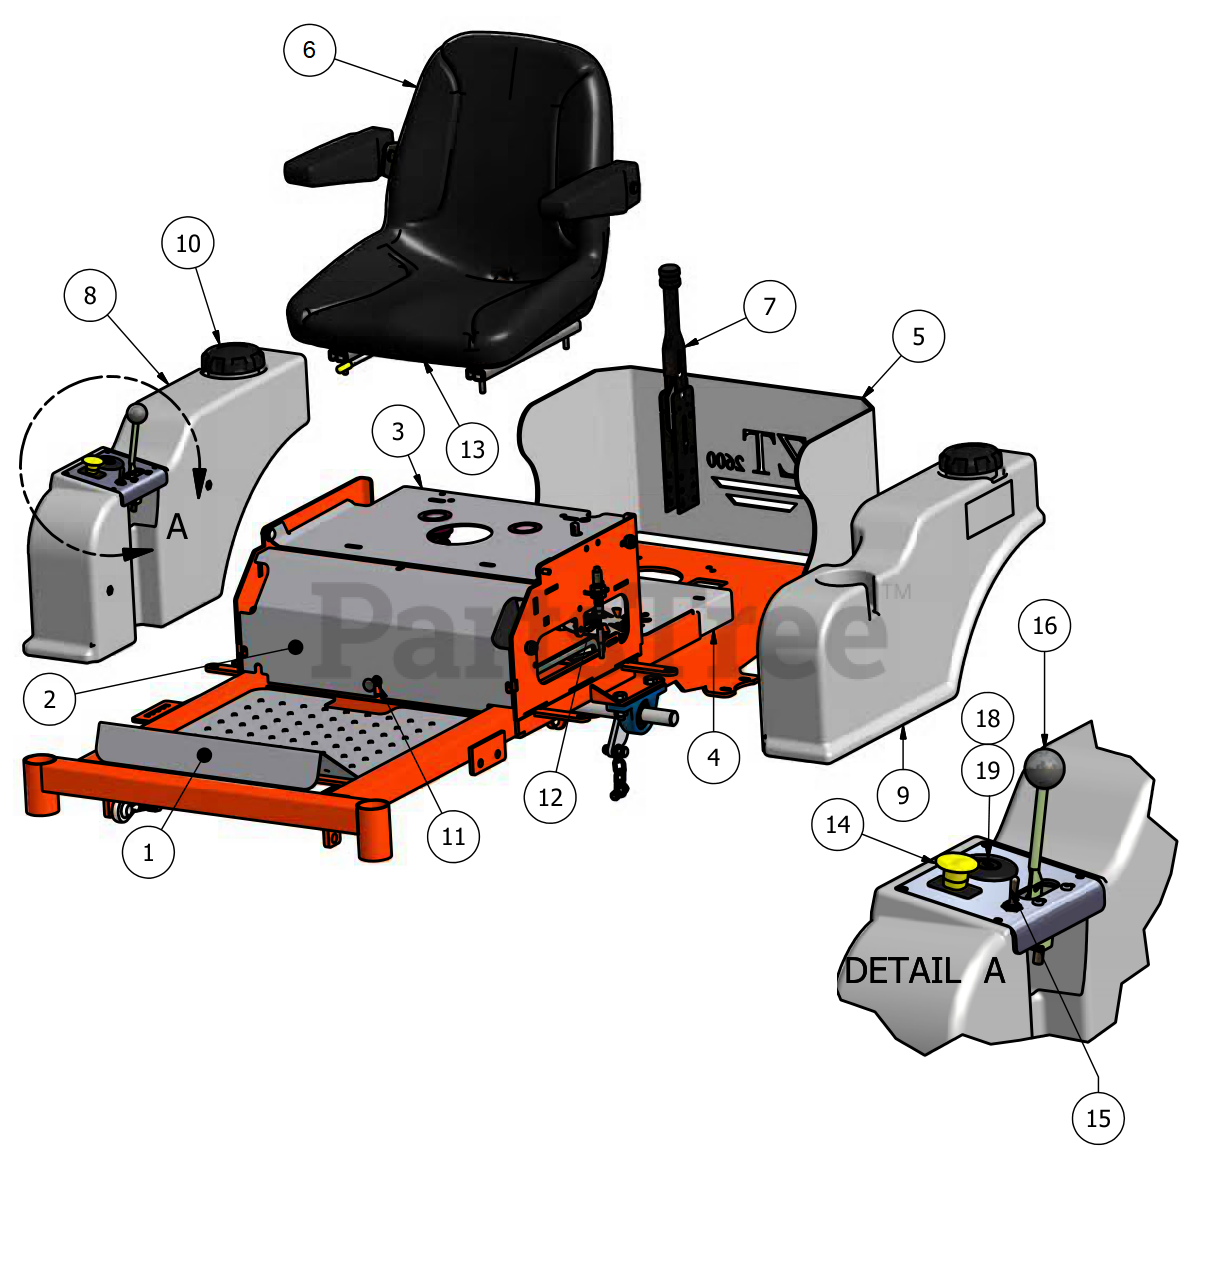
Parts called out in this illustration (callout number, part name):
1	ZT Floor Panel
2	Cooler Cover
3	Seat Mounting Plate
5	ZT Rear Plate
6	Seat Assembly
7	Hand Brake
8	Right Tank
12	Brake Cable
13	Seat Saftey Switch
14	PTO Engager
17	Tachometer
18	Ignition Switch
